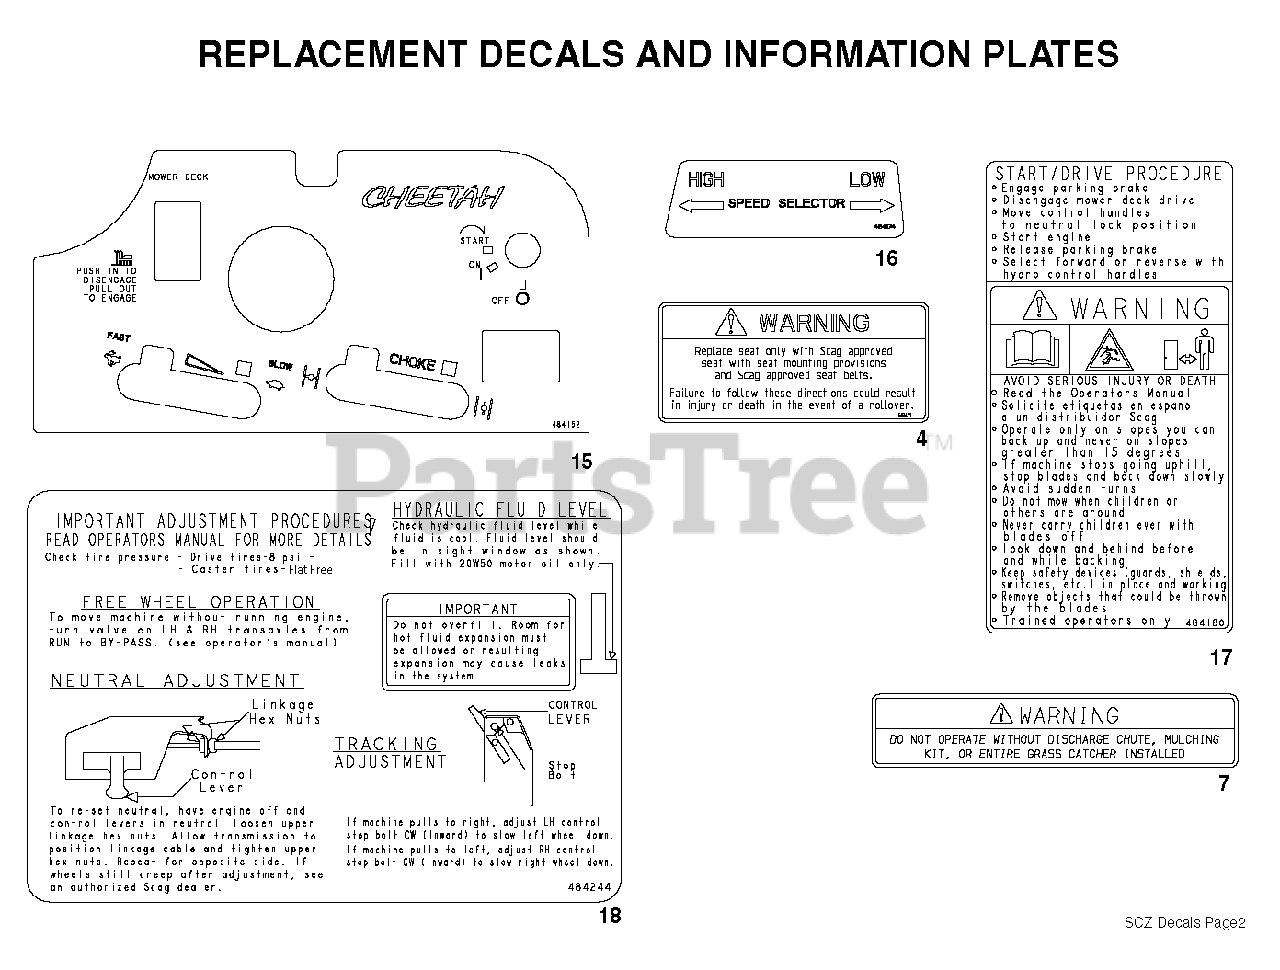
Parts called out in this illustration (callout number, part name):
4	Decal, Seat Replacement
7	Decal, Warning
15	Decal, Instrument Panel - SCZ
16	Decal, Speed Control
17	Decal, Start / Drive
18	Decal, Adjustments - SCZ
